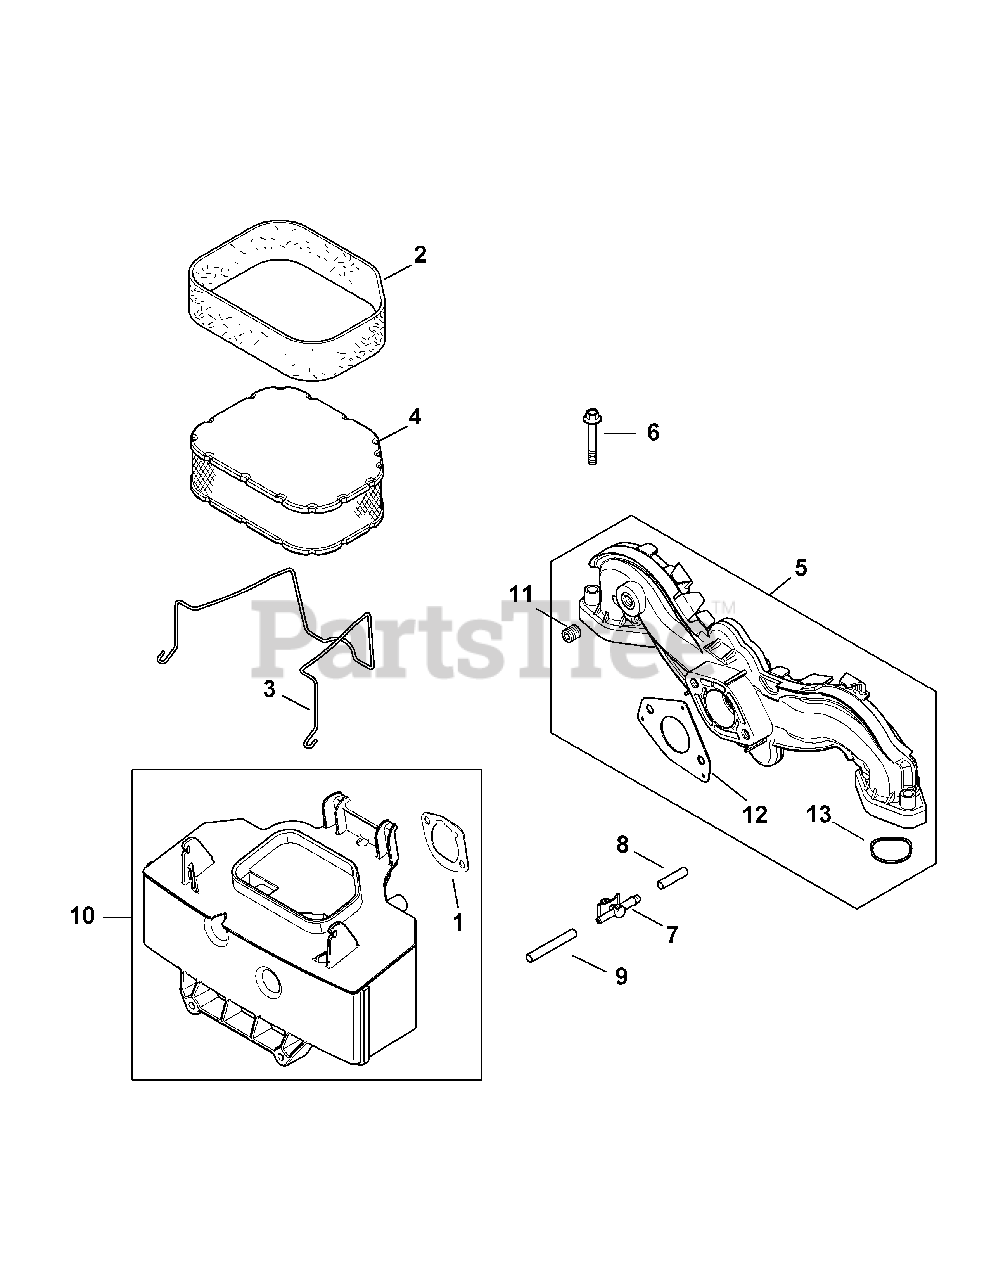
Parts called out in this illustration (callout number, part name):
1	Air Cleaner Base Gasket
2	Pre-Cleaner Element
3	Air Cleaner Element Latch
4	Air Filter & Pre-Cleaner Elements
5	Intake Manifold Kit
6	Flange Screw, M6 x 1.0 x 40
7	Evaporative Connector
8	Evaporative Mask
9	Evaporative Hose, 20"
10	Air Cleaner Base
11	Pipe Plug, 1/8
12	Carburetor Gasket
13	Intake Port O-Ring
